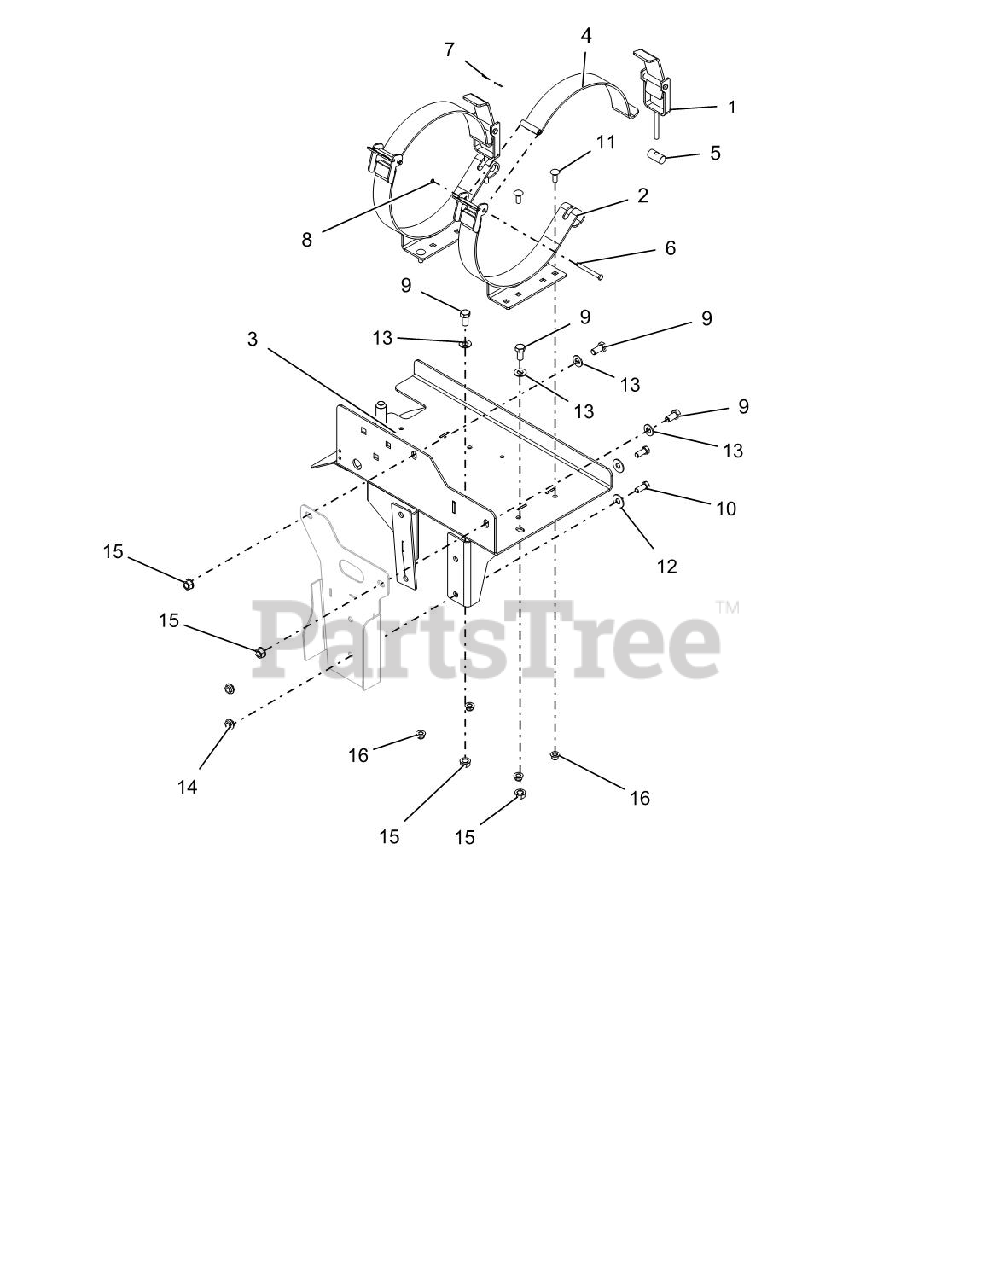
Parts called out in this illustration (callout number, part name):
1	ASM, LP TANK HANDLE CLAMP
2	WLDMT, CLAMP LP TANK-BLACK
3	LH LP TANK MTG W/SAFETY DECAL
4	LP TANK CLAMP W/SAFETY DECAL
5	PIVOT, LP CLAMP HANDLE
6	PIN, LP CLAMP
7	MAGNET, .75X.060, LP CLAMP
8	RG-RTNG-EXT .312X.025
9	BLT-HEX .50-13X1.00 GR5 YWZC
10	BLT-HEX .44-14X1.00 GR5 YWZC
11	BLT-RDHDSQNK .38-16X1.00 G5 YWZC
12	WSHR-FL-STL..50X1.25X.083 YWZ
13	WSHR-FL-STL.531X1.06X.095YWZC
14	NUT-LK-NYL-FLG .44-14 YWZC
15	NUT, LK-TOP-FLG .50-13 YWZC
16	NUT-LK-NYL-FLG .38-16 YWZC
